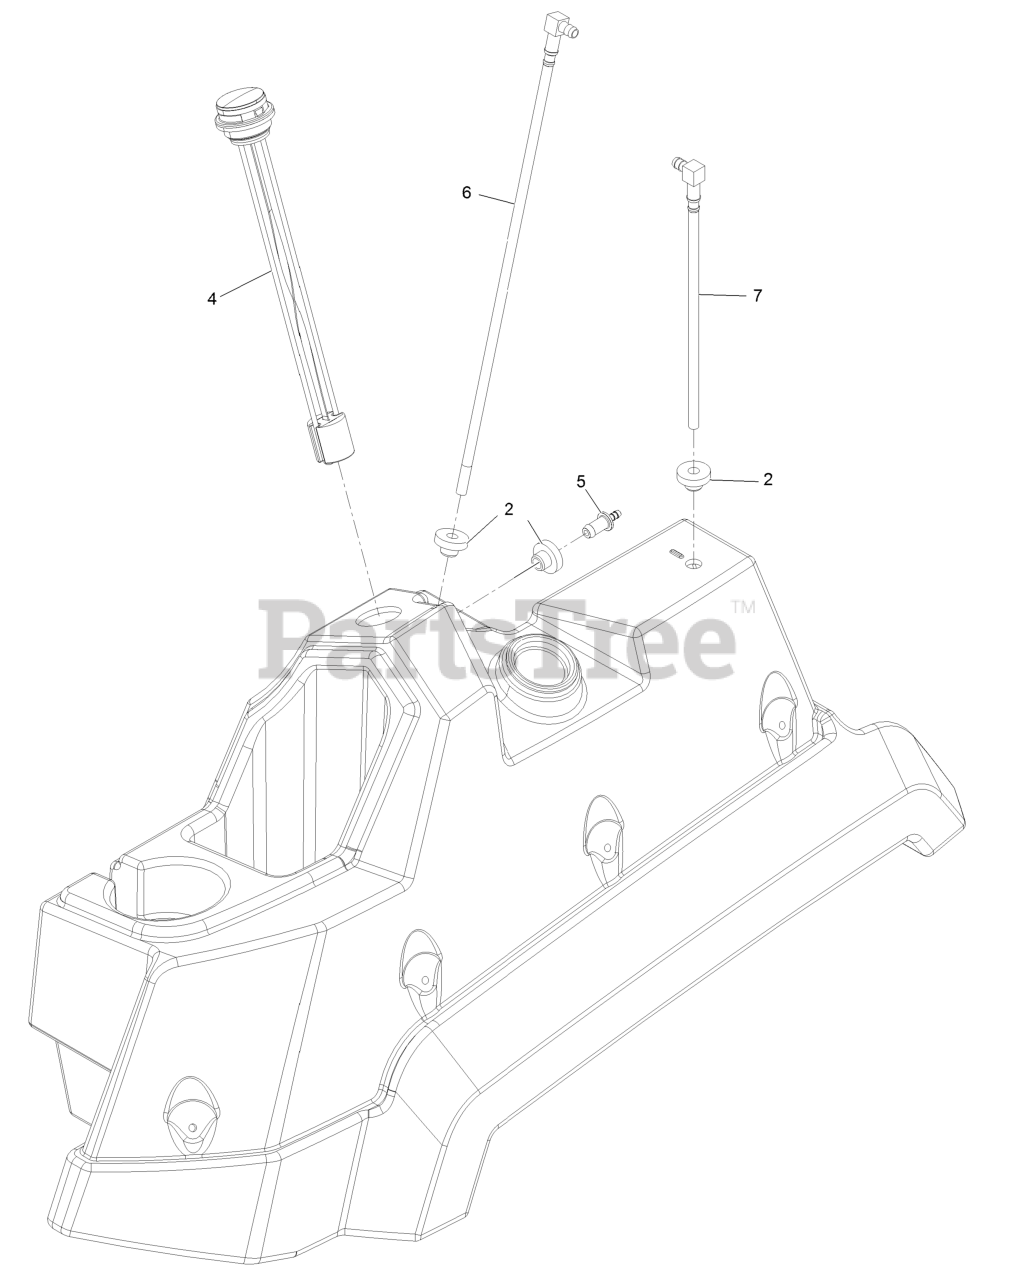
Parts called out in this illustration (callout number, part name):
2	Bushing
4	Gauge-Fuel
5	Fitting-Orifice, Straight
6	Pick-Up-Fuel
7	Return-Fuel
